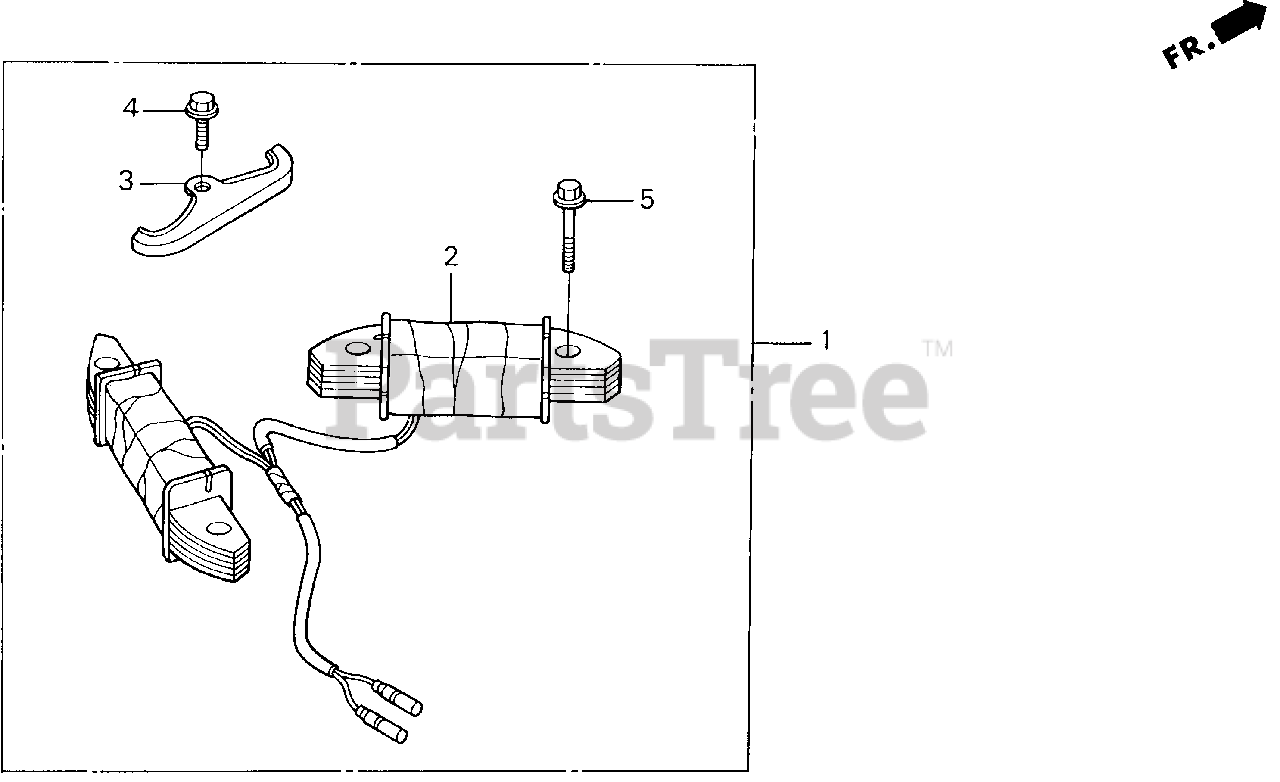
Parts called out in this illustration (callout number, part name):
1	COIL KIT, CHARGE (10A)
2	COIL ASSY., CHARGE (12V-10A)
2	COIL ASSY., CHARGE (12V/10A)
3	HOLDER, WIRE (B)
4	BOLT, FLANGE (6X12)
5	BOLT, FLANGE (6X32)
